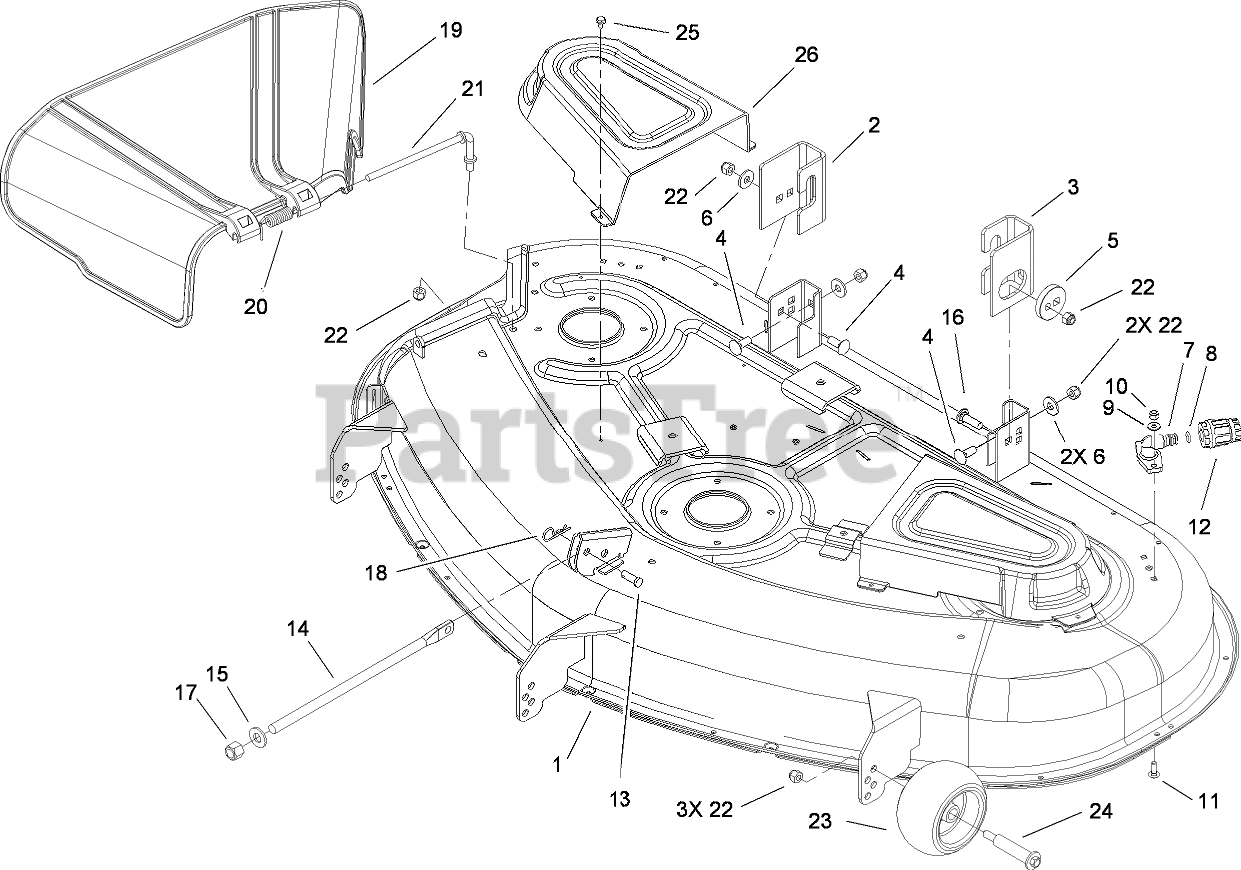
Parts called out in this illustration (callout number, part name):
1	50 INCH DECK ASM
2	BRACKET-HANGER, RIGHT REAR
3	BRACKET-HANGER, LEFT REAR
4	BOLT-CARR
5	ECCENTRIC
6	WASHER-HARDENED
7	FITTING-WASHOUT
8	O-RING
9	WASHER-FLAT
10	NUT-LOCK, NI
11	BOLT-CARR
12	CONNECTOR-HOSE
13	PIN-CLEVIS
14	ROD-LIFT
15	WASHER-THRUST
16	SCREW-CARR
17	NUT-LOCK, NI
18	PIN-HAIR
19	DEFLECTOR
20	SPRING-TORSION
21	ROD-PIVOT
22	NUT-LOCK, NI
23	ROLLER-SCALP, ANTI
24	BOLT-SHOULDER
25	SCREW-HWHTF
26	COVER-BELT
